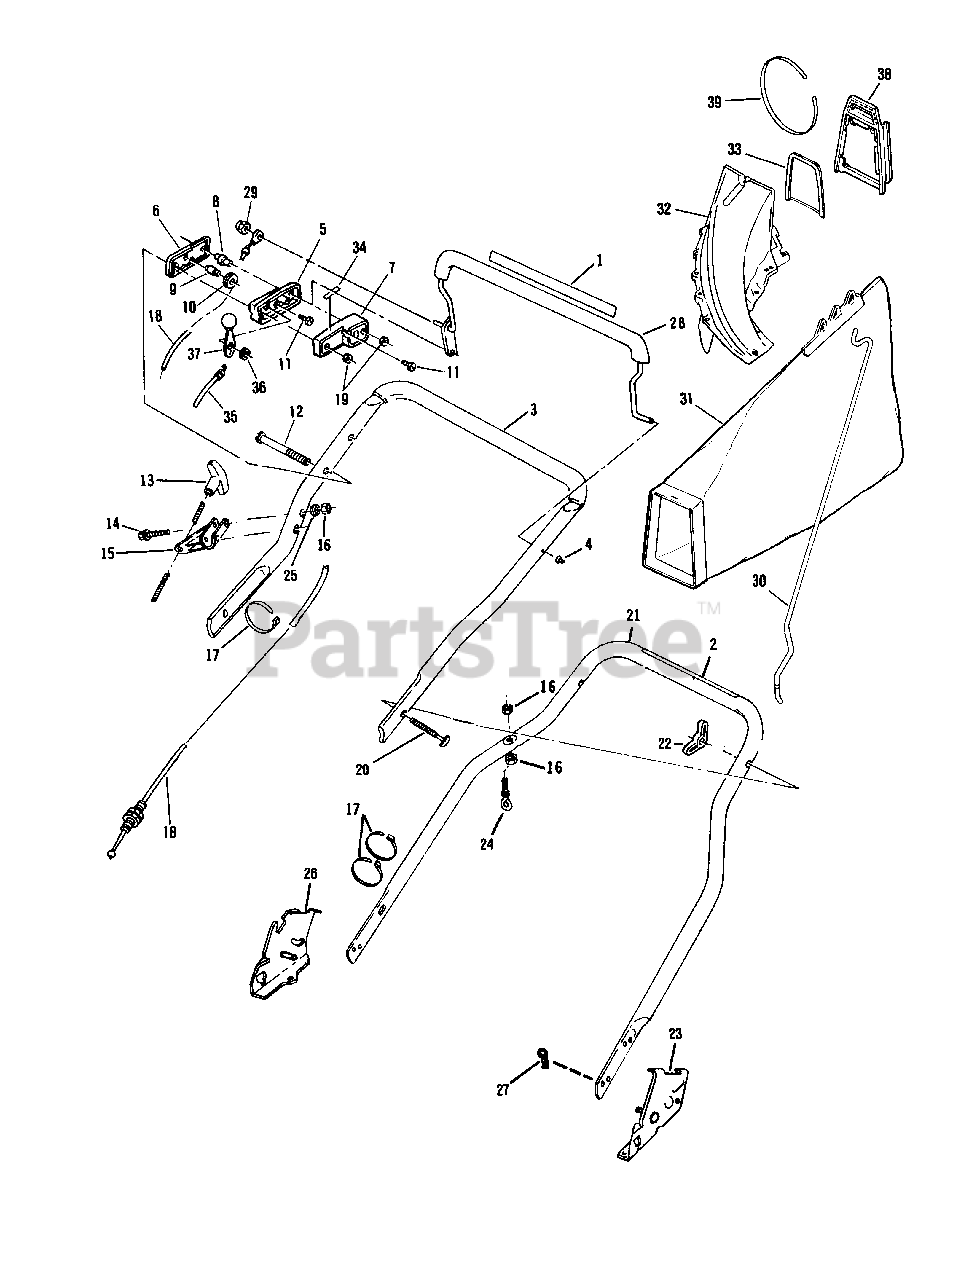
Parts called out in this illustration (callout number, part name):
1	Decal-Engine/Blade Control
2	Decal-Starting Instructions
3	Top Handle
4	Pushnut
5	Control Case-Center
6	Control Case-Outer
7	Control Case-Inner
8	Column
9	Pin
10	Pulley
11	Screw
12	Screw
13	Handle-Starter
14	Screw-Truss Head
15	Rope Guide Assembly
16	Locknut
17	Tie Strap
18	Control Cable Assembly
19	Nut-Hex-Centerlock
20	Screw
21	Handle-Bottom
22	Nut
23	Bracket-Handle-L.H.
24	Eyebolt
25	Washer
26	Bracket-Handle-R.H.
27	Hair Pin-Handle Bracket
28	Control Lever and Nut Assembly
29	Nut-Acorn
30	Grass Bag Rod
31	Grass Bag
32	Chute Assembly
33	Brace-Chute
34	Decal-Throttle
35	Cable-Throttle
36	Washer-Spring
37	Lever and Knob Assembly
38	Adapter-Chute
39	Strap
